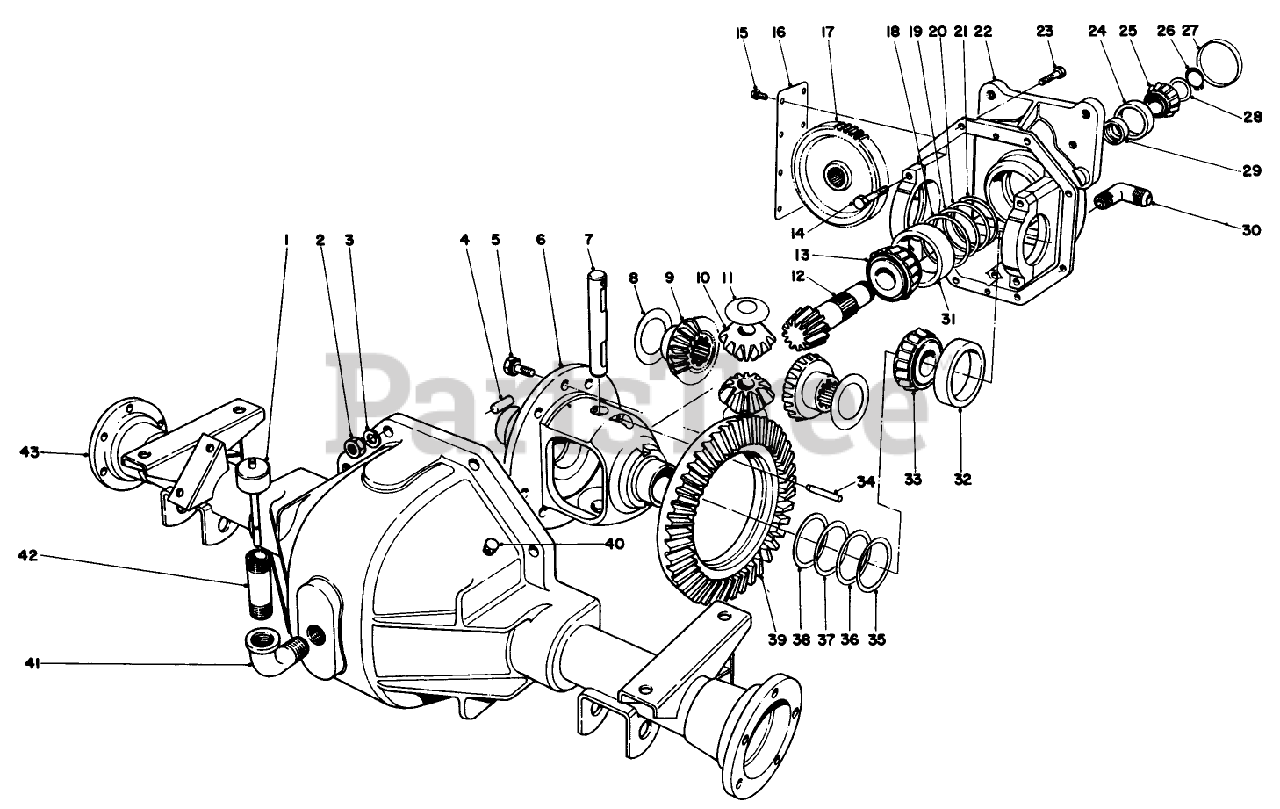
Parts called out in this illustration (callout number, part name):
1	DIPSTICK
2	NUT-HEX
3	WASHER-LOCK
4	PIN-DOWEL
5	SCREW-GEAR, DRIVE
6	CASE-DIFFERENTIAL
7	SHAFT-MATE, PINION
8	WASHER-THRUST
11	WASHER-THRUST, PINION
13	BEARING-ROLLER, CONE TAPER
15	SCREW
16	COVER-GEAR
18	SHIM-PINION (.003)
19	SHIM-PINION (.005)
20	SHIM-PINION (.010)
21	SHIM-PINION (.030)
23	SCREW-HH
24	BEARING-CUP
25	CONE-BEARING
26	RING-SNAP
27	PLUG-CUP
28	SHIM-BEARING, FRONT
29	SPACER-BEARING
30	90 DEG FITTING
31	BEARING-TAPER, CUP
32	CUP-BEARING, ROLLER
33	BEARING-ROLLER, CONE
34	PIN-ROLL
35	SHIM-BEARING, DIFFERENTIAL (.003)
36	SHIM-BEARING, DIFFERENTIAL (.005)
37	SHIM-BEARING, DIFFERENTIAL (.010)
38	SHIM-BEARING, DIFFERENTIAL (.030)
39	Ring Gear
41	FITTING-ELBOW-90
42	PIPE NIPPLE
43	LOWER HSG , TUBE AND MTG. PAD WA.
